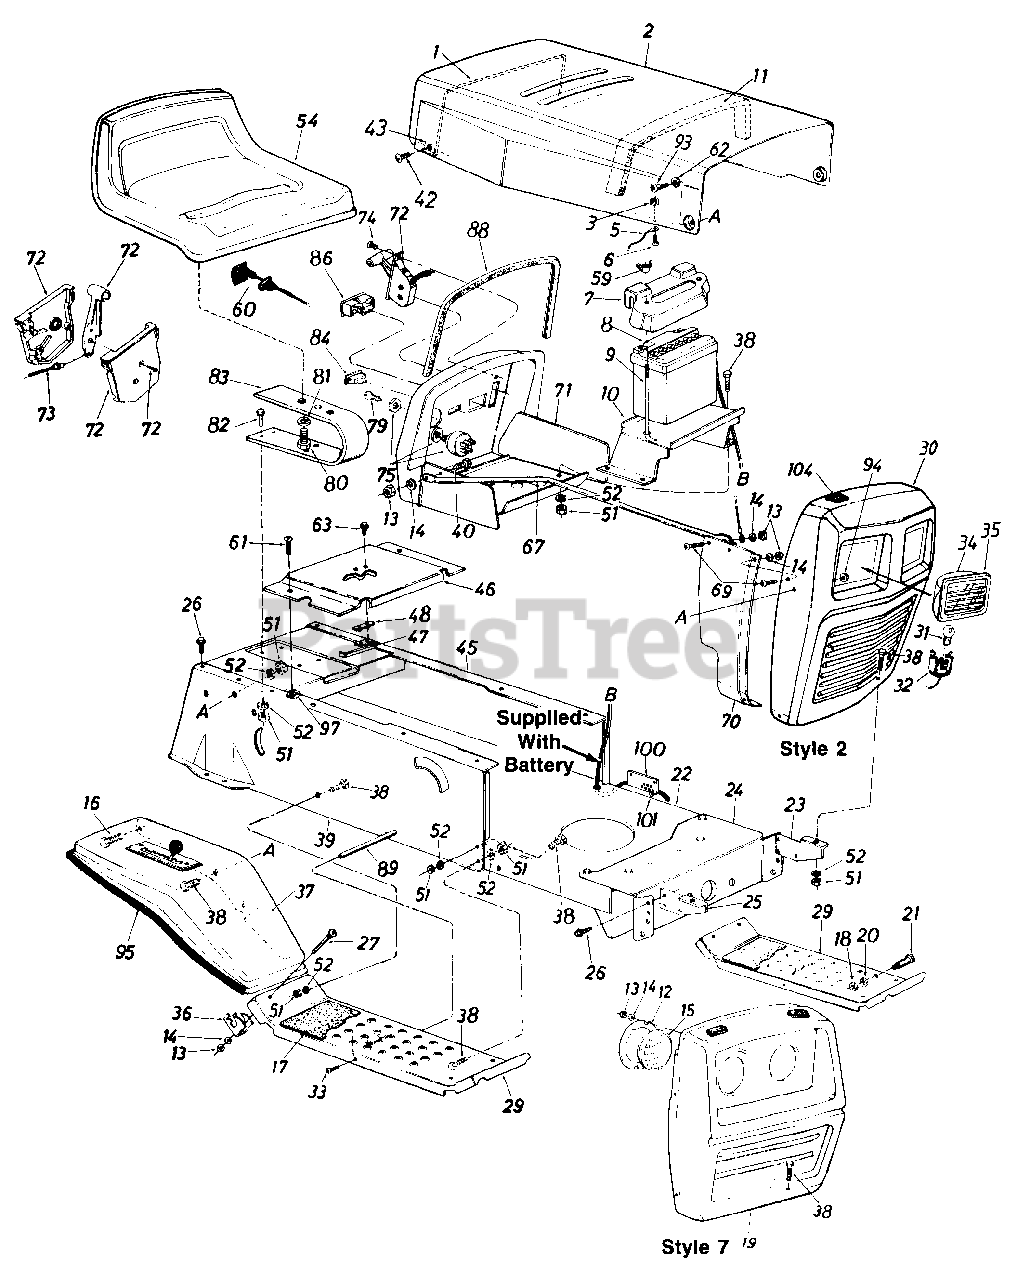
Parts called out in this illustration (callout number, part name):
1	Hood Spring
2	Hood
3	Hex Sems Nut #10-24 Thd.
5	Hood Stop 7" Lg.
6	Truss Hd. Scr. #10-24 x 1/2"
7	Battery Cover
8	12 Volt Battery
9	Battery Hold Down Rod
10	Battery Bracket
11	PVC Foam-Strip
12	Headlight Retainer [Used with Grille Ref No. 19
13	Hex Nut 1/4-20 Thd.
14	L-Wash. 1/4" I.D.
15	Headlight [Used with Grille Ref No. 19
16	Hex Wash. Hd. Tap Scr. 1/4 x 3/8" Lg.
17	Foot Pad
18	Hex Nut 3/8-16 Thd.
21	Shld. Bolt .50" Dia. x .84
22	Lower Frame
23	Grille Mount Brkt.-L.H. [Used with Grille Ref No. 30 (Style 2)]
24	Front Pivot Brkt.
25	Grille Mount Brkt.-R.H. [Used with Grille Ref No. 30 (Style 2)]
26	Hex Wash. Hd. AB-Tap Scr. 5/16 x .75" Lg.
27	Carr. Bolt 1/4-20 x 2.00" Lg.
29	Running Board
32	Lamp Socket
33	Truss Mach. Scr. 5/16-18 x .75" Lg.
34	Headlight Housing
35	Lens
36	Fender Clamp
37	Fender
39	R.H. Side Frame
40	Hex Bolt 1/4-20 x .62" Lg.
42	Self-Tap Scr. .5" Lg.
43	Hood Spring Retainer
45	L.H. Side Frame
46	Shift Cover
47	Reverse Safety Switch
48	Insulator Nut Plate
51	Hex Nut 5/16-18 Thd.
52	L-Wash. 5/16" I.D.
54	Seat Ass'y.
59	Wing Nut 1/4-20 Thd.-Plastic
60	Choke Control 44 on Lg.
61	Truss Mach. Tap Scr. #10 x .50" Lg.
62	Washer .39" I.D. x .62" O.D.
63	Hex Wash. Hd. AB-Tap Scr. #8 x .50
67	Grille Support Rod-R.H.
70	R.H.-Grille Side Panel
71	Dash Panel Ass'y.
72	Throttle Control Box Ass'y.
73	Throttle Control Wire-35"
74	Truss Mach. AB-Tap Scr. #10 x .5" Lg.
75	Ignition Switch
79	Ignition Key
80	Hex Bolt 1/2-13 x 1.00" Lg. (Grade 5)
81	L-Wash. 1/2" I.D.
82	Hex Bolt 5/16-18 x 1.0"
83	Seat Spring 5.5" High
84	Light Switch
86	Ammeter
88	Molding Strip 27" Lg.
89	Running Board Rod
93	Shld. Bolt .375 Dia. x .125
94	L-Nut 1/4-28 Thd.
95	Trim Strip 31.0" Lg.
97	Speed Nut #10Z
100	Brake Cable Bracket
101	Cable Tie
104	Foam Strip 3/8 x 1-1/8 x 1-1/2
